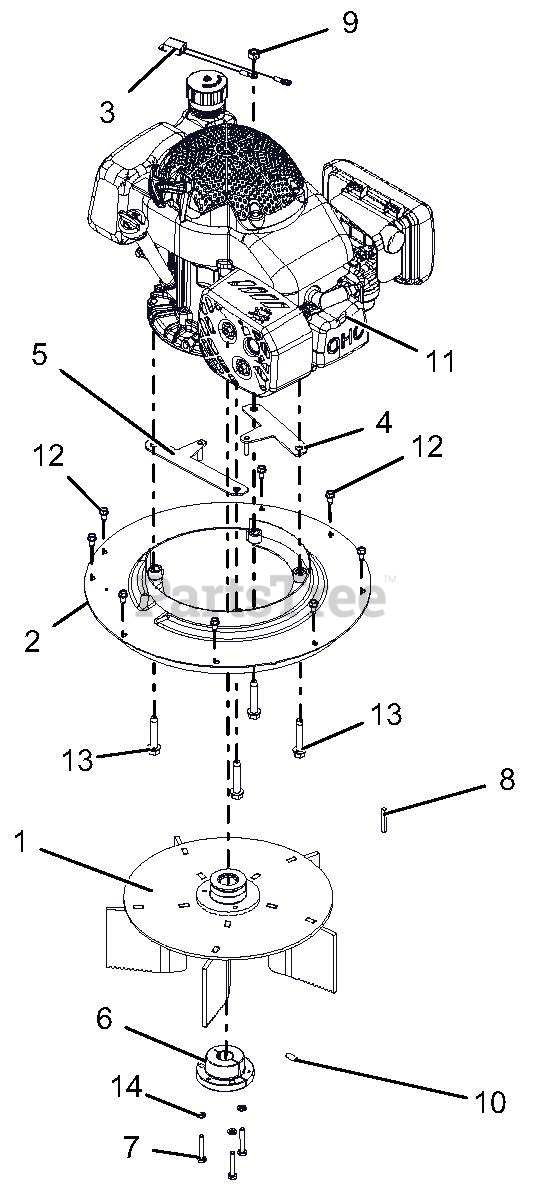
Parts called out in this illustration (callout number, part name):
1	WLDMT, IMPELLER - APV TAPER
2	WLDMT, ENGINE PLATE-RED
3	HARNESS, WIRE APV
4	WLDMT, BRKT - APV BELT FNGR S
5	WLDMT, BRKT - APV BELT FNGR R
6	BUSHING, TAPER -SPLIT 7/8" (SDS)
7	BLT-HEX .25-20X1.50 GR5 YWZC
8	KEY-SQ .188X.188X1.50 SAE 8630
9	NUT-LK-CTR .38-16 YWZC
10	SCR-SET, 25-20X.75 SKHCUPDL REV
11	ENGINE, SUBARU - EA190 (CARB)
12	SCR-TAP .25-20X.50 HWH TR YWZ
13	SCR-TAP .38-16X2.00 HWH TR YZ
14	WSHR-LK .25X.062 REG YWZC
